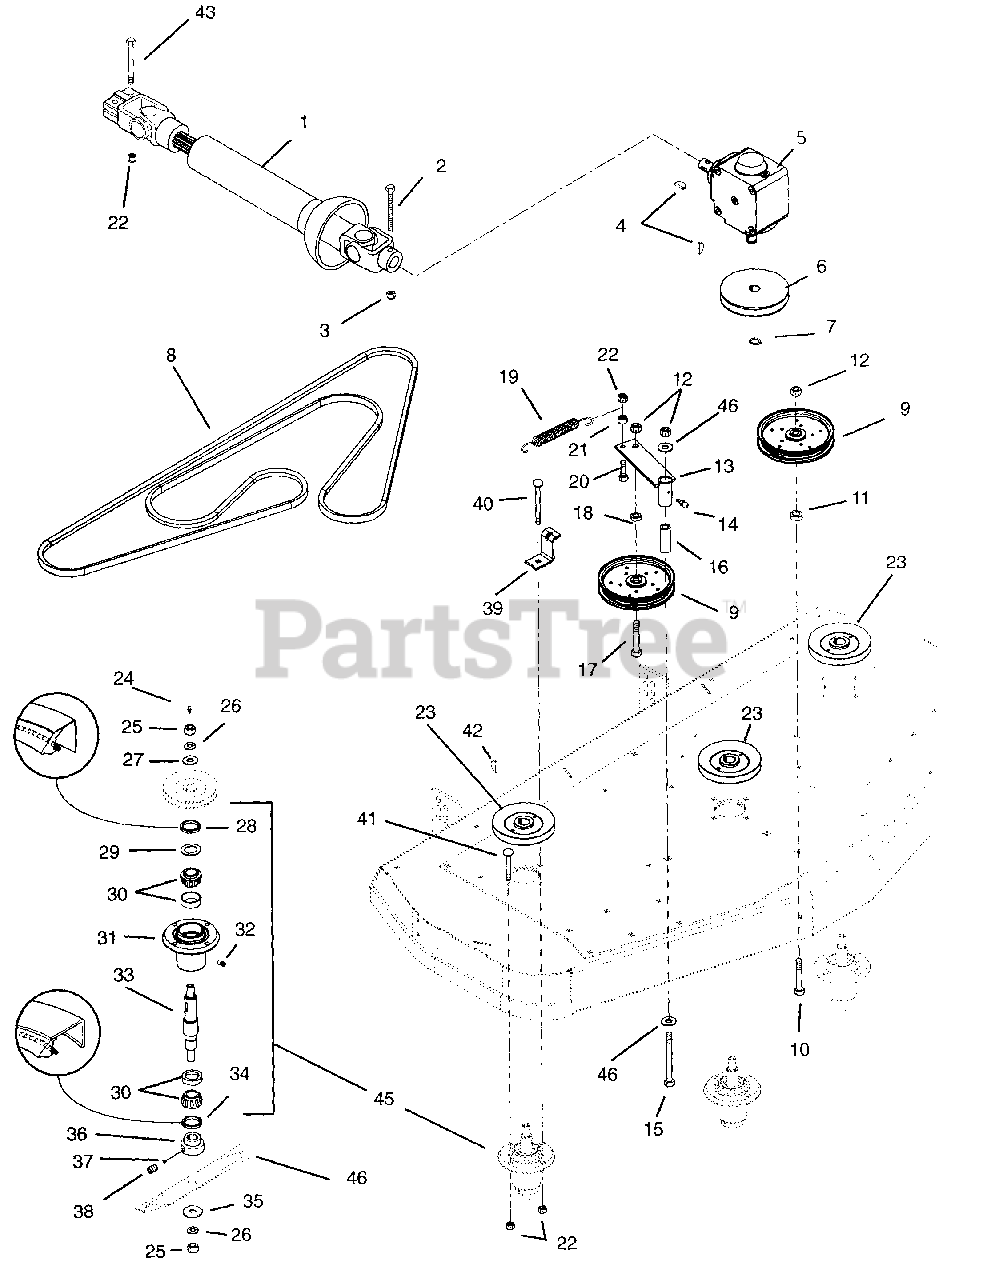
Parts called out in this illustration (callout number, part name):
1	Universal Joint Assembly
2	Bolt-Hex .31-18 x 2.25 Grade 5
3	Nut-Locking-Center .31-18
4	Key-Woodruff .25 x .875
5	Gearbox, Right Angle 1:1.025
6	Sheave, Gearbox
7	Ring-Retaining-External .821 x .078
8	V-Belt, BRMA 77.50 x .672
8	V-Belt, A-RMA 59.40 x 17/32
9	Idler-Flat-Pulley 6.75 x .510
9	Pulley-Idler 4.00 x .380
10	Bolt-Hex .50-13 x 2.75 Grade 5
11	Spacer .562 x .975 x 1.00 Steel
12	Nut-Locking-Center .50-13
13	Weldment, Idler Pivot
14	Fitting-Lube .25-28 x .256
15	Bolt-Hex .50-13 x 3.75 Grade 5
16	Spacer .505 x .855 x 2.50
17	Bolt-Hex .50-13 x 3.25 Grade 5
18	Spacer .516 x .875 x .300
19	Spring-Tension .120 x .845 x 6.50
20	Bolt-Hex .38-16 x 1.00 Grade 5
21	Nut-Hex .38-16
22	Nut-Locking-Center .38-16
23	Weldment Sheave
23	Sheave
24	Fitting-Lube .25-28 x .256
25	Nut-Hex .62-11
26	Washer-Locking .62 x .156
27	Washer-Flat-Steel .687 x 1.312 x .150
28	Seal 1.987 x 1.500 x .313
29	Washer-Flat-Steel 1.007 x 1.542 x .062
30	Assembly, Bearing Cup and Cone
31	Bearing Housing
32	Relief Fitting-Grease
33	Shaft Spindle
34	Seal 1.987 x 1.375 x .313 Cross
35	Washer
38	Screw Set .25-20 x .25
39	Anchor, Spring
40	Bolt-Round Head Square Neck .38-16 x 2.00 Grade 5
41	Bolt-Round Head Square Neck .38-16 x 1.25 Grade 5
42	Key-Woodruff .25 x 1
43	Bolt-Hex .38-16 x 1.50 Grade 5
44	Washer-Flat-Steel .531 x 1.06 x .095
45	Spindle Assembly
46	Blade Kit, PM-360 60"
46	Blade Kit, PM-360 60" CE
46	Blade Kit, PM-360 50"
46	Blade Kit, PM-360 50" CE
